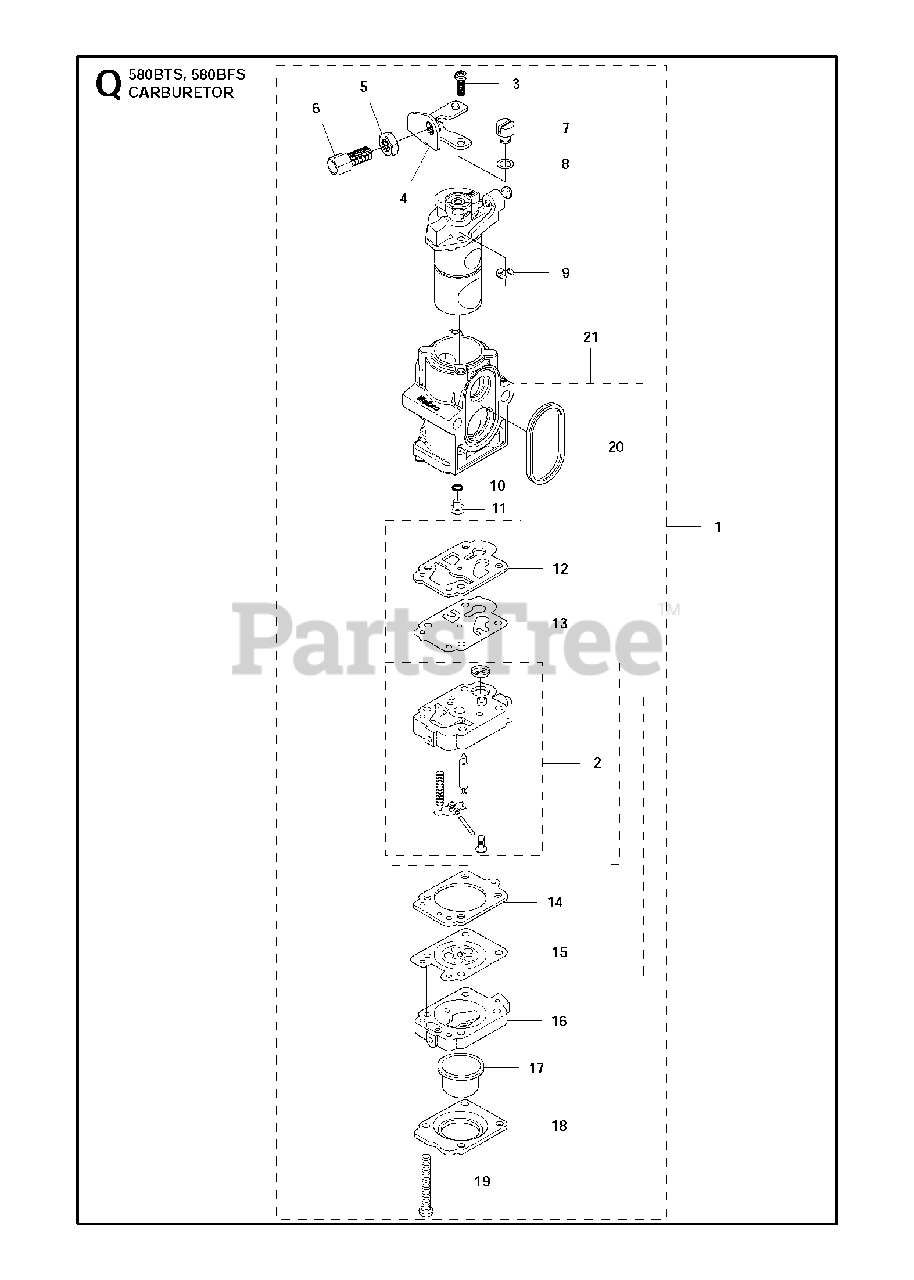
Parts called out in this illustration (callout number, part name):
1	CARBURETOR
2	BODY-A-PUMP
3	SCREW
4	BRACKET
5	NUT
6	ADJUSTER
7	SWIVEL
8	WASHER
9	RING
10	O-RING
11	JET #61
12	GASKET
13	DIAPHRAGM
14	GASKET
15	DIAPHRAGM
16	BODY
17	PUMP
18	1OVER
19	SCREW
20	RING
21	GASKET KIT
